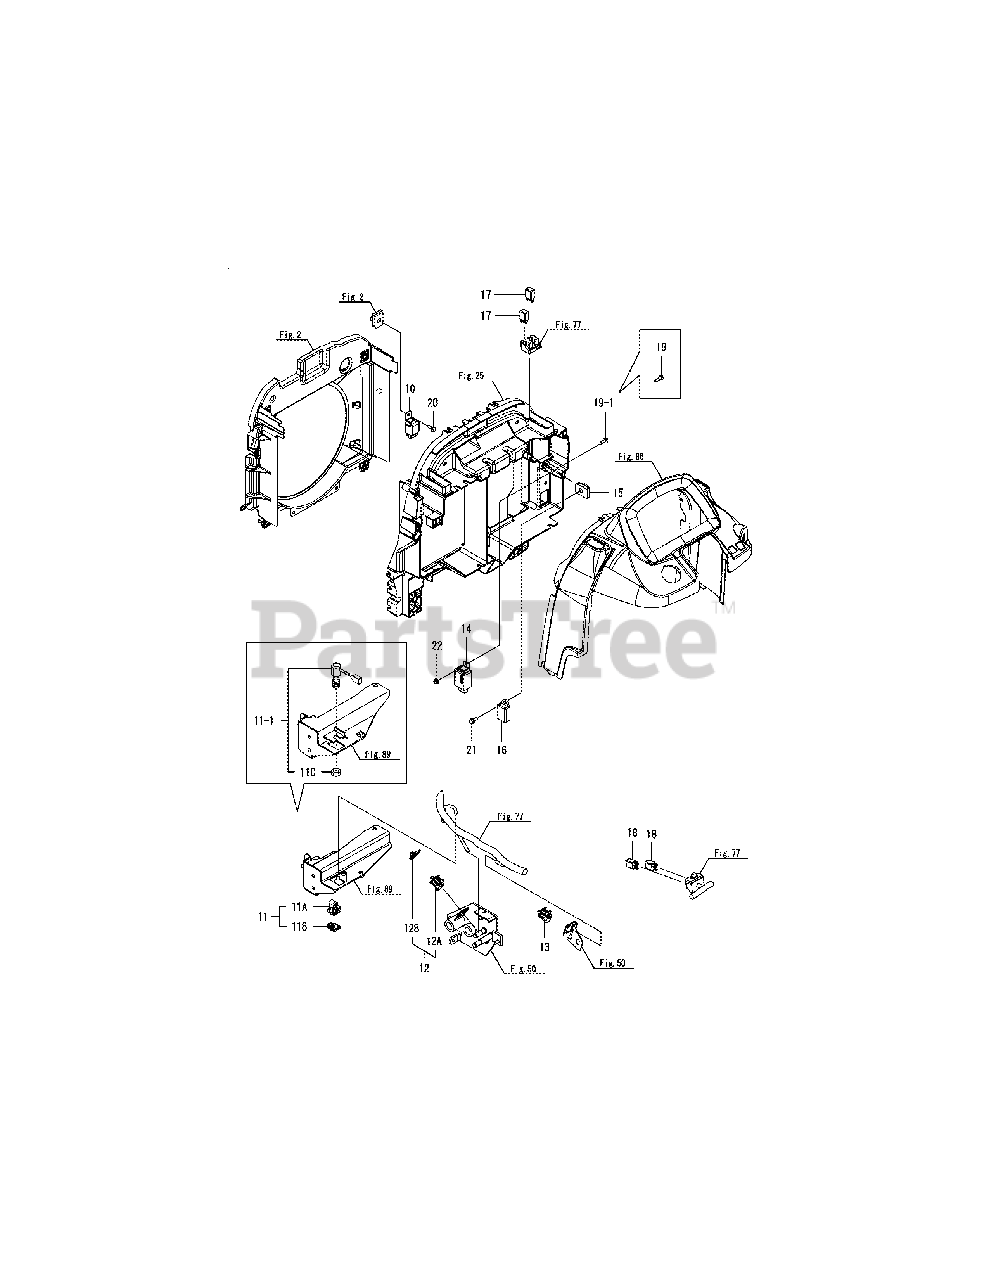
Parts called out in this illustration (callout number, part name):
10	Relay, Starter
11	Switch Nc Assy, Pedal
11-1	Switch, Brake Lamp
11A	Switch Nc, Pedal
11B	Protective Cover
11C	Lock Nut M12 Plated
12	Switch Nc Assy, Pedal
12A	Switch Nc, Pedal
12B	Protective Cover
13	Switch, Seat, Delta, As
16	Timer, Section 1
17	Relay, Acm 13211M01
18	Relay, Acm 13211M01
19-1	Bolt, 6 X 16
